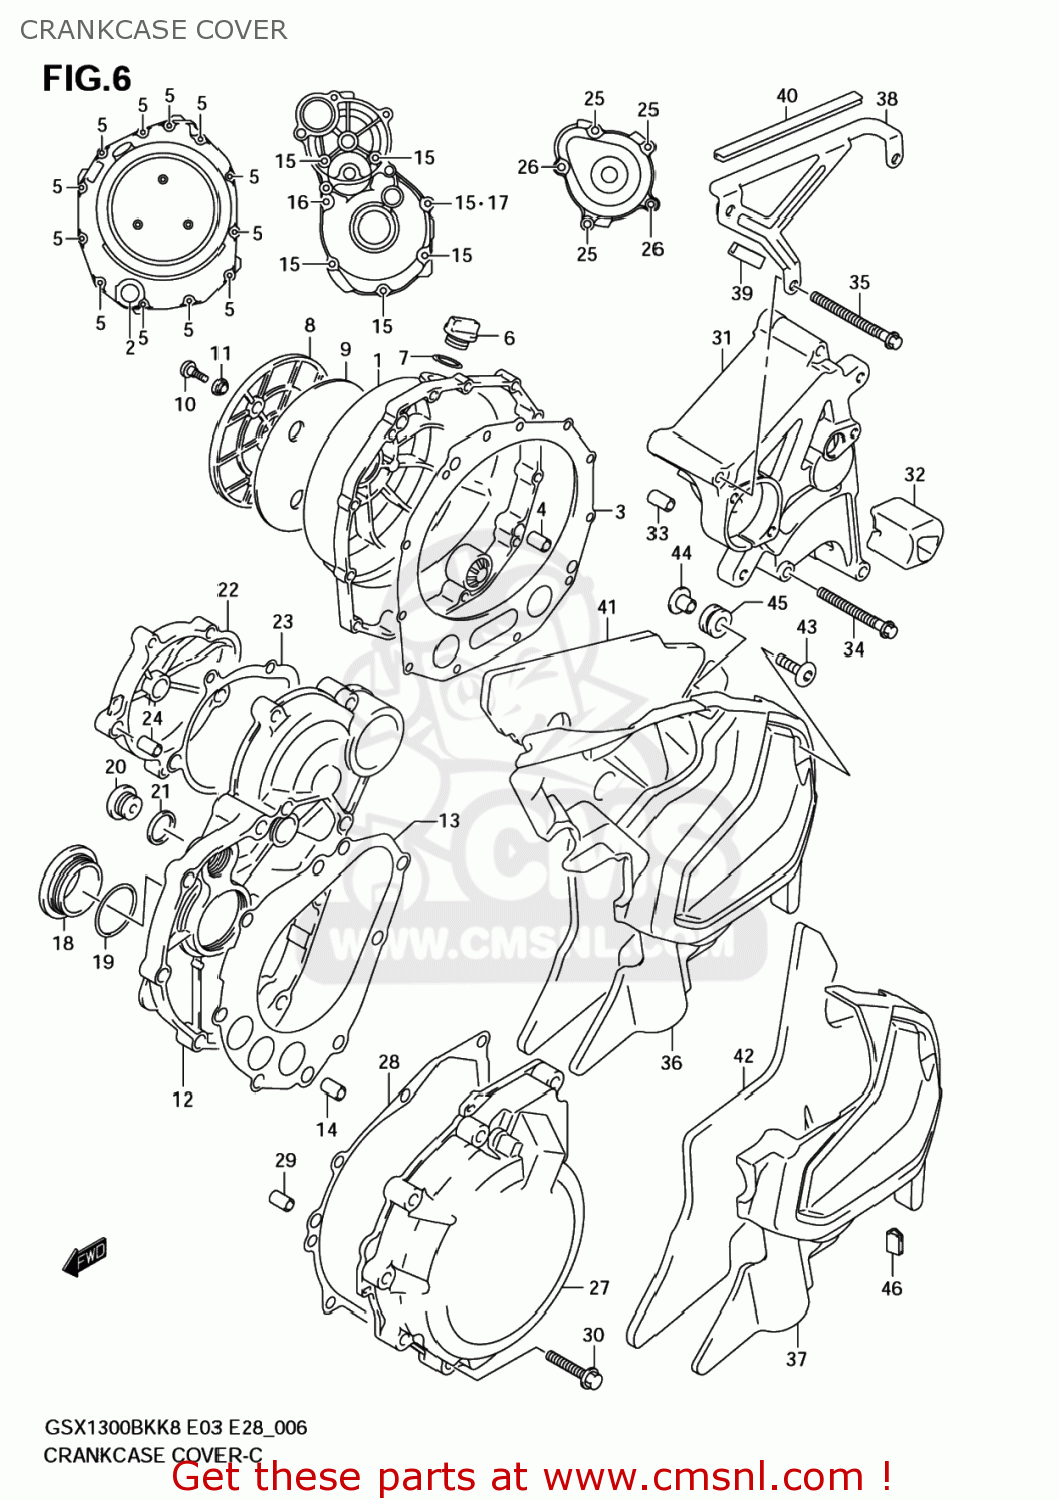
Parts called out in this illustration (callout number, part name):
1	COVER,CLUTCH
2	LENS,OIL LEVEL CHECK
3	GASKET,CL COVER (NAS)
4	PIN
5	BOLT(6X30)
6	PLUG,ENGINE OIL FILLER
7	O RING(D:3.1,ID:16.8)
8	COVER,CLUTCH OUTER
9	CUSHION,CLUTCH OUTER COVER
10	SCREW(6X16)
11	WASHER,CLUTCH OUTER COV SCREW
12	COVER,STARTER CLUTCH
13	GASKET,STARTER CLUTCH COVER (NAS)
14	PIN
15	BOLT(6X25)
16	BOLT(6X35)
17	GASKET(5.8X13X1.2) (NAS)
18	PLUG
19	O RING(D:3.1,ID:32.7)
20	PLUG,16X8
21	GASKET(16X22X2) (NAS)
22	CAP,STARTER IDLE GEAR
23	GASKET,START IDLE GEAR CAP (NAS)
24	PIN
25	BOLT(6X25)
26	BOLT(6X35)
27	COVER,MAGNETO
28	GASKET,MAGNETO COVER (NAS)
29	PIN
30	BOLT(6X30)
31	COVER,ENGINE SPROCKET
32	PROTECTOR,ENGINE SPRKT COVER
33	PIN
34	BOLT(6X55)
35	BOLT(6X65)
36	COVER,ENGINE SPROCKET OUTER
37	COVER,ENGINE SPROCKET OUTER
38	BRACKET,ENGINE SPROCKET COVER
39	MOLD,SPRKT COVER BRACKET NO.1
40	MOLD,SPRKT COVER BRACKET NO.2
41	CUSHION,ENGINE SPROCKET COVER
42	CUSHION,ENGINE SPROCKET COVER
43	SCREW(6X20)
44	WASHER
45	CUSHION
46	MOLDING
